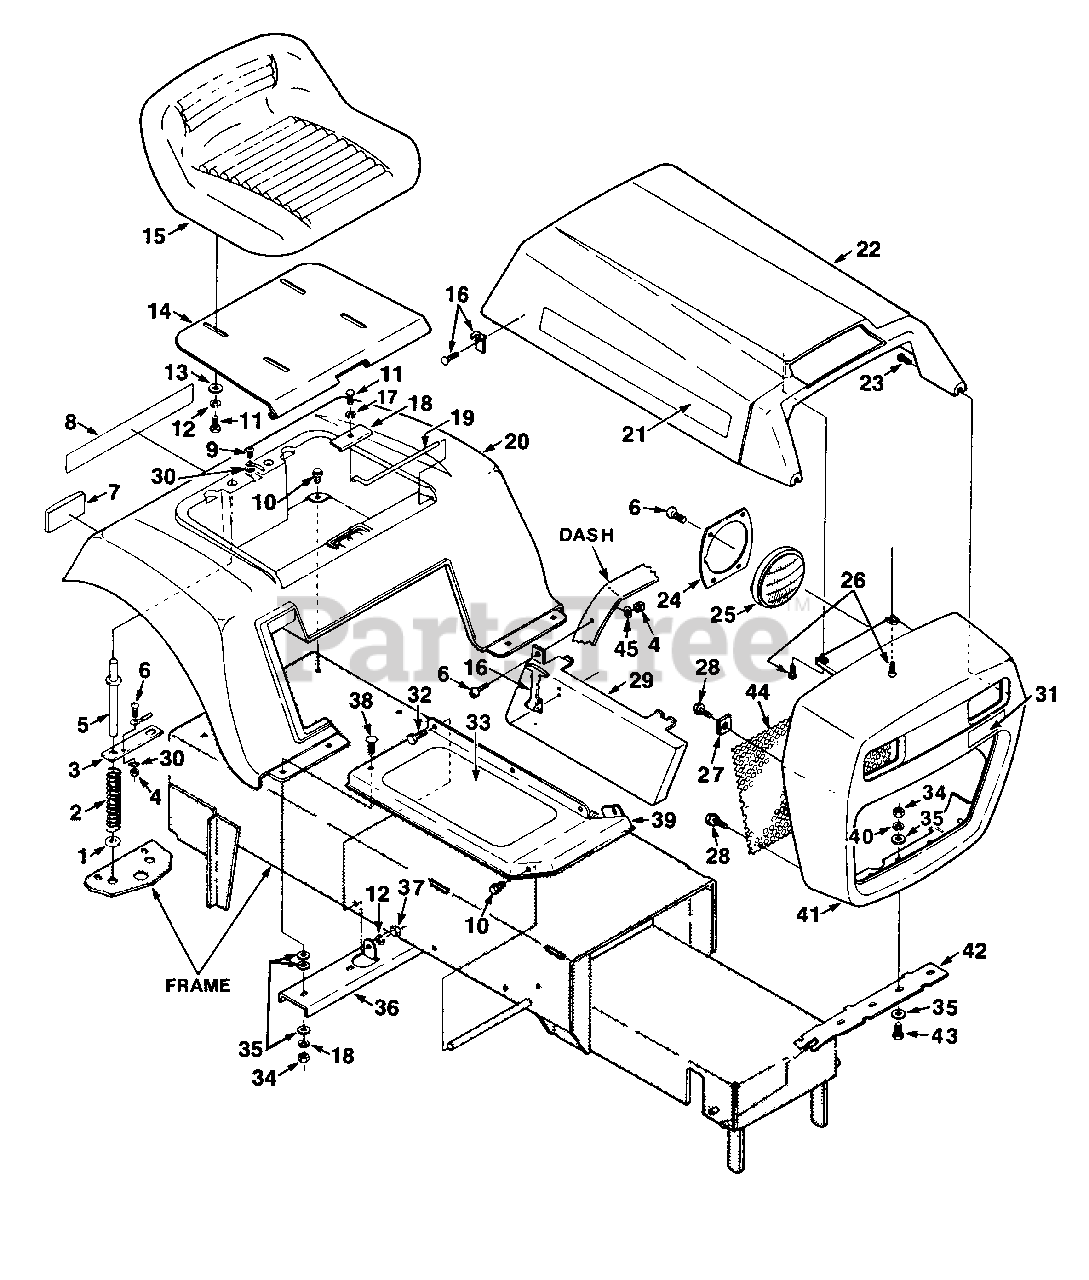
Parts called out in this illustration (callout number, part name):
1	WASHER- Insulation
2	SPRING- Compression
3	CONTACT- Interlock
4	NUT
5	PIN- Seat support
7	REFLECTOR- Reflex
8	DECAL- 11"
11	SCREW-Cap
12	WASHER
13	WASHER
14	PAN- Seat
15	SEAT- Jacobsen
17	WASHER- Lock 1/4
18	BRACKET- Hitch
19	ROD, Hinge
21	DECAL- 17 1/2"
23	SCREW- 1/4 x 14 x 1
24	RETAINER- Light
25	LIGHT- Head
26	SCREW- Tap hex hd.
28	SCREW 1/4-14 x 1/2
29	PANEL- Side R.H.
30	WASHER- Lock #10
31	DECAL- 11 HP (LTX-11)
32	SCREW- Cap 5/16-18 x 5/8
33	PAD- Footboard
34	NUT- Hex 1/4-20
35	WASHER- Plain 1/4
36	BRACKET- Footboard
37	NUT- Hex 5/16-18
38	BOLT- 1/4-20 x 1
39	FOOTBOARD, RH
40	WASHER- Lock 1/4
42	HINGE- Grille
43	SCREW- 1/4-20 x 5/8
44	GRILLE SCREEN
